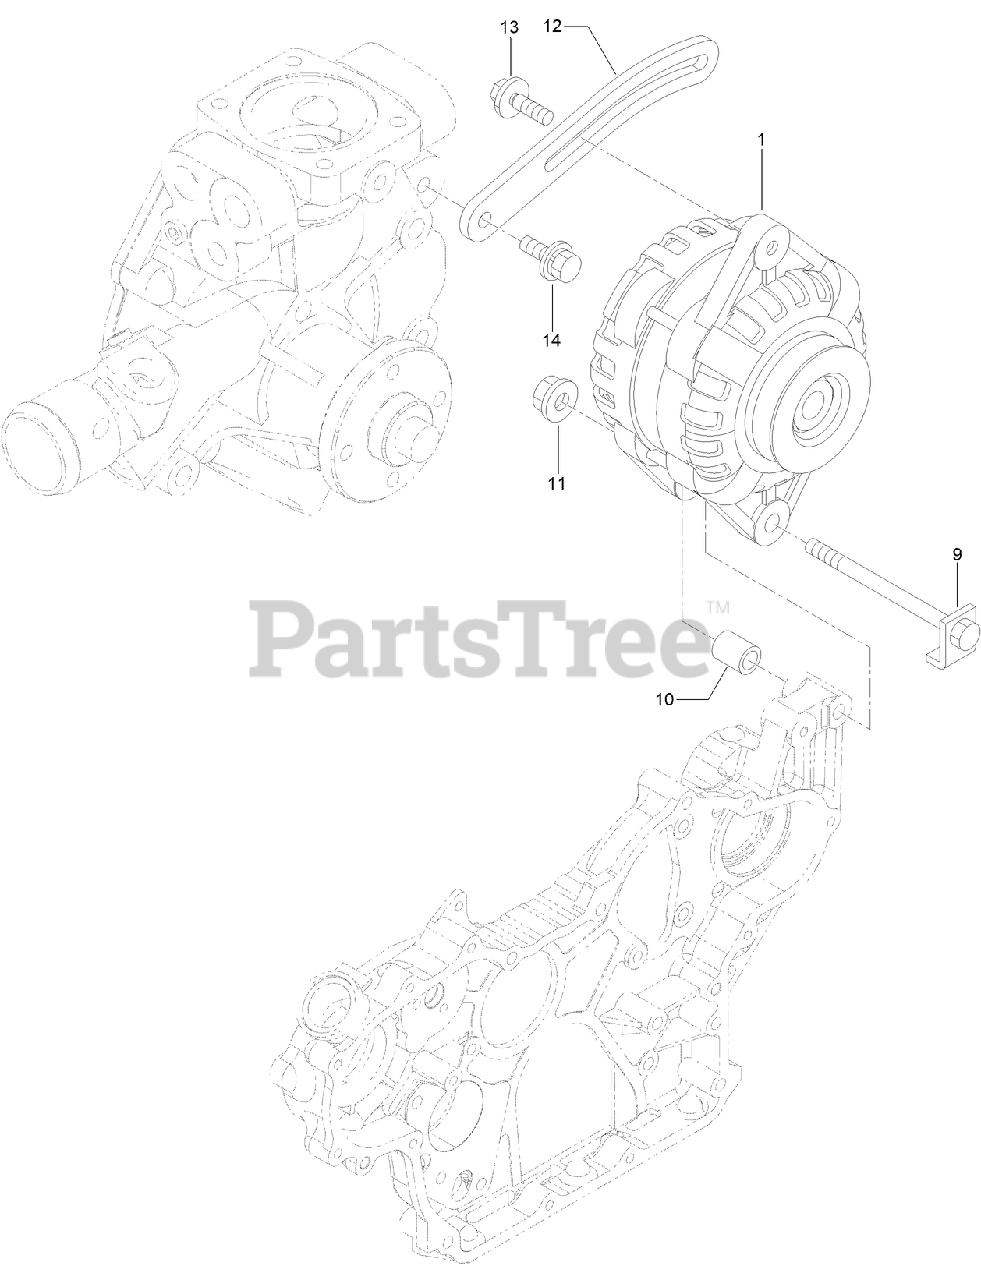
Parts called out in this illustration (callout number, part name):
1	ALTERNATOR-12V
9	BOLT-STOPPER
10	PIECE-DISTANCE
12	ARM-ADJUSTOR
13	BOLT-ADJUSTING
